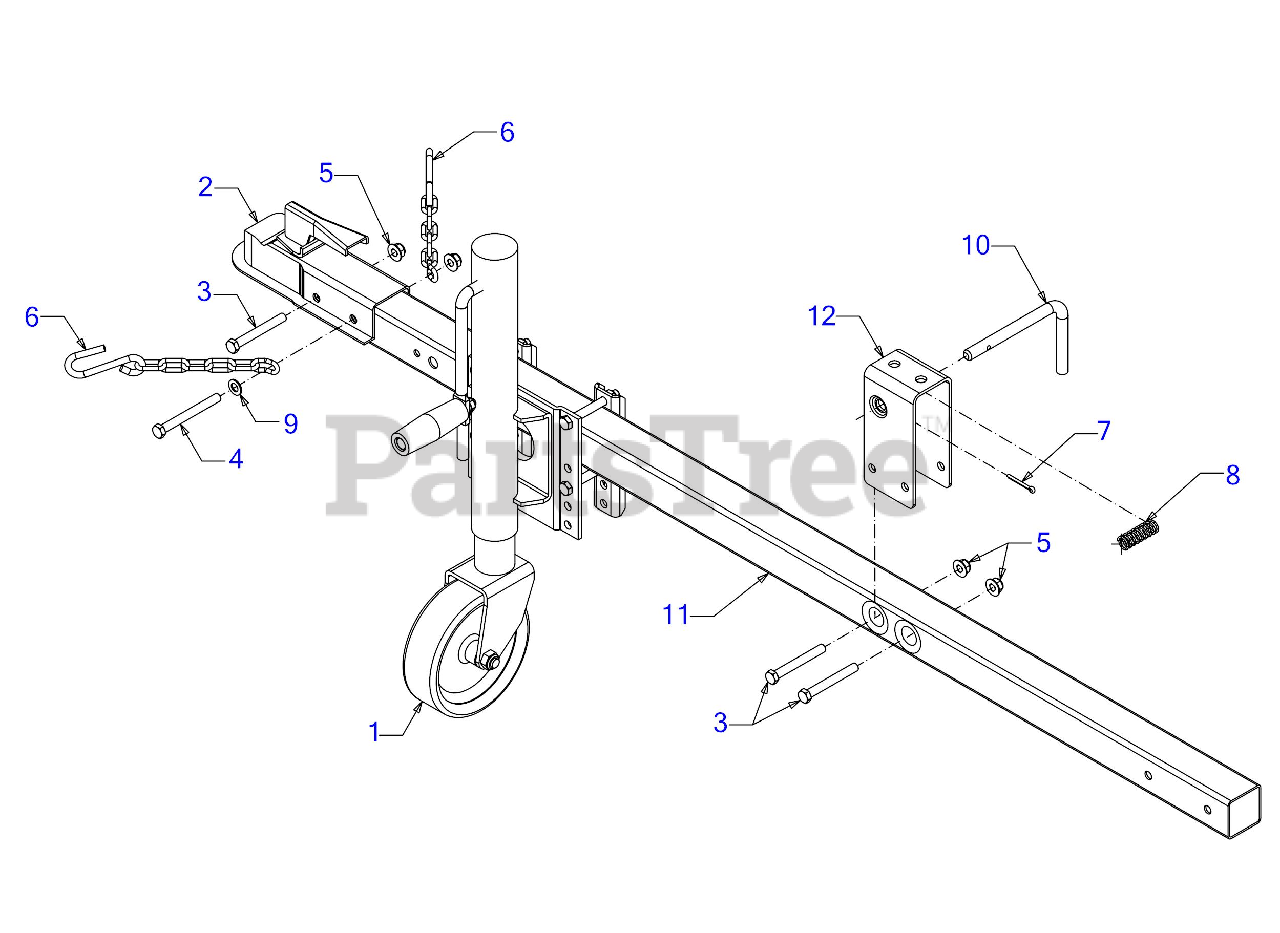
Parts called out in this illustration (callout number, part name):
1	ADJUSTING STAND
2	HITCH COUPLING ASSEMBLY
3	SCREW 3/8-16 x 3 GR8
4	SCREW 3/8-16 x 3.50 GR5
6	LOGSPLITTER TOW CHAIN
7	COTTER PIN-5/32 DIA
8	COMPRESSION SPRING
9	FLAT WASHER
10	LATCH ROD
